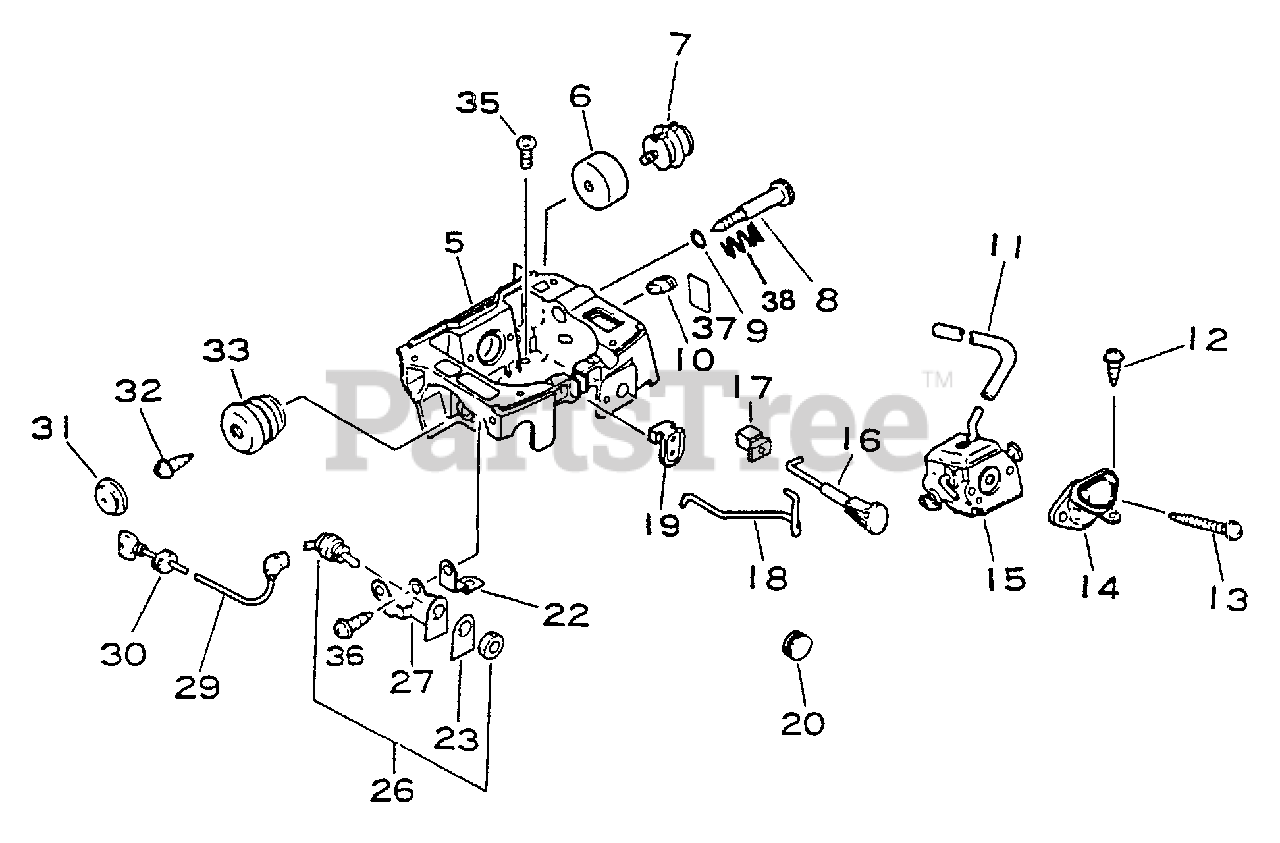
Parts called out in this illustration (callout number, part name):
5	CASE, CARBURETOR
6	PLATE, CUSHION
7	CUSHION
9	O-RING 6 MM
11	PIPE, IMPULSE
12	SCREW 5×14
13	SCREW 5×53
14	GASKET
15	CARBURETOR
16	ROD, CHOKE
17	GROMMET
18	ROD, THROTTLE
19	GUIDE, THROTTLE ROD
22	PLATE - GROUND
23	LABEL - SWITCH
26	SWITCH, ON-OFF
27	BRACKET, SWITCH
29	LEAD - GROUND
31	CAP, CUSHION
33	CUSHION
35	SCREW - 5×20
36	SCREW 5×10
37	LABEL, CAUTION - IDLE
